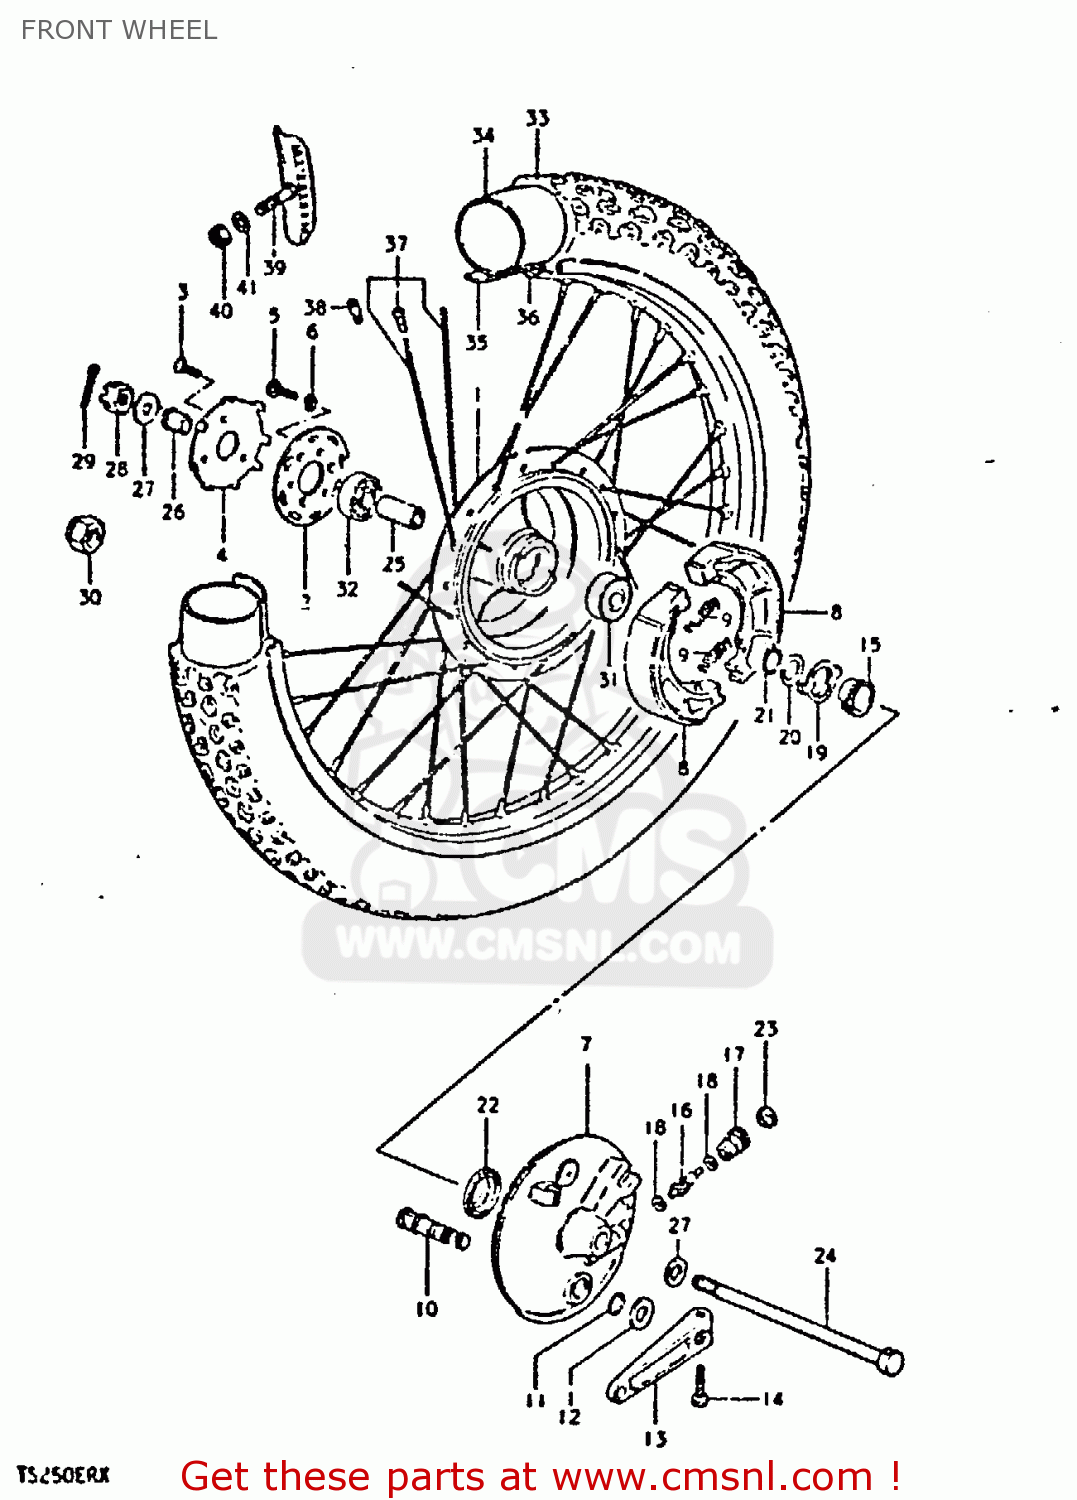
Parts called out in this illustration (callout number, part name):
1	DRUM,FRONT HUB
2	FLANGE,FR HUB,R
3	SCREW
4	RETAINER,FR HUB BEARING,R
5	BOLT, UPPER
6	LOCK WASHER
7	PANEL,FRONT HUB
8	SHOE,BRAKE (MCA)
9	SPRING
10	CAM,FRONT BRAKE
11	O-RING,BOSS
12	WASHER (15X24X1.6)
13	LEVER,FRONT BRAKE CAM
14	BOLT
15	GEAR,SPEEDOMETER
16	PINION,SPEEDOMETER
17	BUSHING,SPEEDOMETER PINION
18	WASHER (5.1X9X0.4)
19	DRIVER,SPEEDOMETER GEAR
20	WASHER(22.5X27X1)
21	CIRCLIP
22	SEAL,OIL(26X38X4)
23	SEAL,OIL(6X10X3)
24	AXLE,REAR
25	SPACER (12.6X19X52)
26	SPACER,FR AXLE,R
27	WASHER
28	NUT, REAR AXLE
29	COTTER PIN
31	BEARING
32	BEARING, RH
33	TIRE,FRONT
34	TUBE
35	PROTECTOR,WHEEL,INNER
36	RIM,FRONT WHEEL
37	SPOKE SET,FR
38	BALANCER,WHEEL (50G)
39	STOPPER,BEAD
40	NUT
41	WASHER
